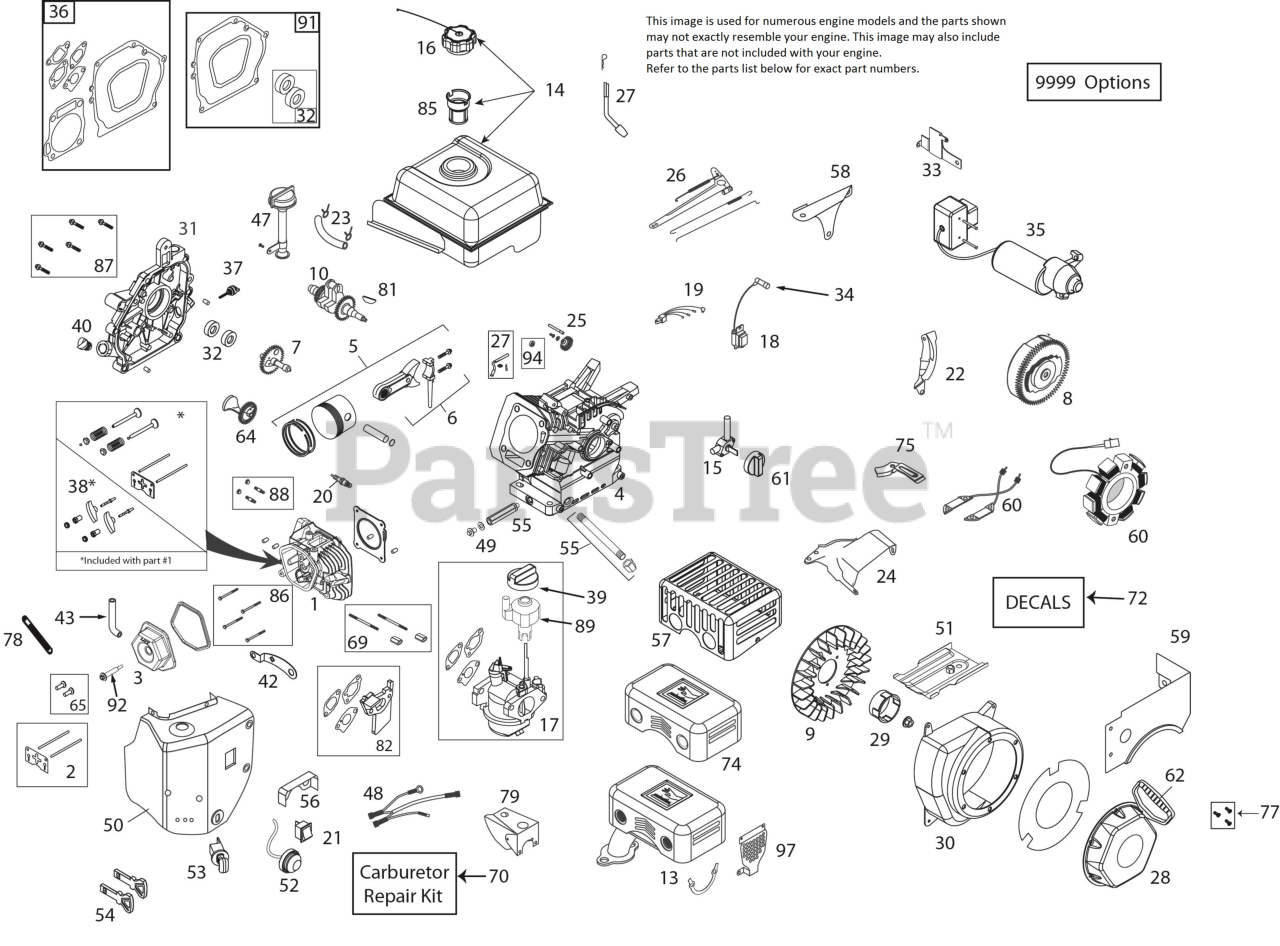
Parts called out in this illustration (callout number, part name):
1	CYLINDER HEAD 420CC
2	PUSH ROD & PLATE KIT (W/GSKT)
3	VALVE COVER (W/GASKET)
5	PISTON AND ROD ASSEMBLY
7	CAMSHAFT - MCR
8	FLYWHEEL - ELECTRIC START
9	COOLING FAN - FLYWHEEL
10	CRANKSHAFT
13	MUFFLER ASSEMBLY - GEN III
14	FUEL TANK ASSEMBLY
15	VALVE-PETCOCK, FUEL TNK ON/OFF
16	FUEL CAP
17	CARBURETOR (WITH IDLE-DOWN)
18	IGNITION COIL (CDI) (STANDARD)
20	SPARK PLUG
23	FUEL HOSE KIT
24	SPEED CONTROL SHIELD (GEN III)
25	GOVERNOR GEAR ASSEMBLY
26	GOVERNOR ARM & LINK KIT
27	GOVERNOR ARM PADDLE
28	RECOIL STARTER, ROUND STYLE
29	STARTER CUP, ROUND STYLE
30	BLOWER HOUSING - MATTE BLACK
31	CRANKCASE COVER
32	OIL SEAL KIT
33	ELECT START SWITCHBOX BRACKET
34	SPARK PLUG BOOT (W/MTL SHIELD)
35	230V EU ELECTRIC STARTER
36	ENGINE GASKET KIT
37	SMALL BLACK OIL DIPSTICK
38	ROCKER ARM KIT (W/GASKET)
39	CHOKE CONTROL KNOB (RED)
40	NON-REMOVABLE PLASTIC PLUG
43	BREATHER TUBE
47	HIGH OIL-FILL TUBE & CAP
48	WIRE HARNESS
49	OIL DRAIN PLUG (W/WASHER)
50	HEATER BOX KIT (369/414CC)
51	SHIELD - CYLINDER
52	PRIMER BULB WITH HOSE
53	KEY SWITCH, STOP-RUN (W/KEYS)
54	KEY, TURN LCT (2/PACKAGE)
55	FRONT OIL DRN PIPE & NUT ASSY
56	CARBURETOR VAPOR SHIELD
57	MUFFLER HEAT SHIELD - GEN III
58	SHIELD - GOVERNOR LINKAGE
59	FUEL TANK SKIRT
60	CHARGING COIL (60-WATT AC)
61	FUEL CONTROL KNOB (RED)
62	STARTER GRIP-SNOW (DELUXE)
64	COUNTER WEIGHT KIT
65	TAPPET KIT (SET OF 2)
69	CARB MTG STUD KIT 414CC
70	CARBURETOR REPAIR KIT
72	ARIENS LABEL KIT
75	SHIELD - FLYWHEEL
77	RECOIL BOLT KIT
78	BREATHER TUBE RETAINING STRAP
79	SHIELD - CARBURETOR COVER
81	WOODRUFF FLYWHEEL KEY 5-PACK
82	CARBURETOR SPACER
85	FUEL TANK STRAINER
86	HEAD BOLT KIT 291-414CC
87	CRANKCASE COVER BOLT KIT 414CC
88	MUFFLER SHOULDER BOLT
89	SPEED CONTROL KNOB
91	CRANKCASE GASKET KIT(369-414)
92	VALVE COVER BOLT (SINGLE BOLT)
94	GOVERNOR SHAFT SEAL
9999	HIGH ALT JET - 414CC L12 CARB
9999	HARDWARE KIT (4 M6X10 FLG BLT)
9999	STARTER SWITCH SCREWS
9999	CLIPS, CARB THROTTLE LINKAGE
